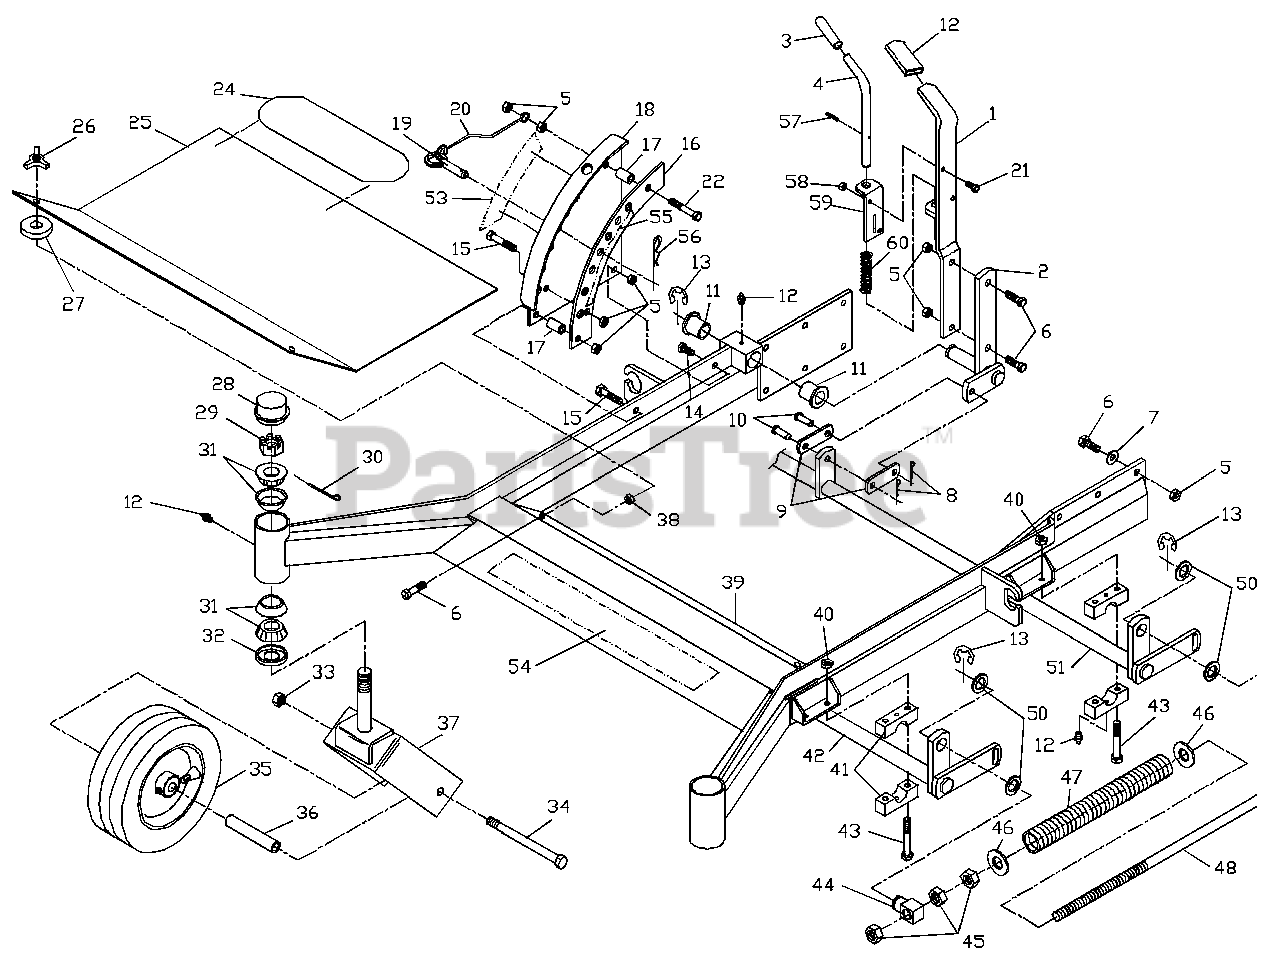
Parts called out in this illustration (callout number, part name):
1	LIFT LEVER
2	DECK LIFT ARM
5	3/8C CENTERLOCK NUT
6	3/8C X 1 1/4 HEX CAP SCREW
7	3/8 DISC SPRING WASHER
8	1/8 X 3/4 COTTER PIN
10	3/8 X 1 1/8 CLEVIS PIN
11	FLANGED BEARING
13	7/8 "E" RING
14	3/8C X 3/4 HEX CAP SCREW
15	3/8C X 2 HEX CAP SCREW
18	PLATE WELDMENT
21	HCS 1/4C X 3/4
22	3/8C X 2 1/4 HEX CAP SCREW
24	ANTI-SKID PAD
25	FOOT PLATE
27	RUBBER WASHER
28	GREASE CAP
29	1" C HEX SLOTTED NUT
30	1/8 X 2 COTTER PIN
31	BEARING W/CUP
33	1/2C NYLOC NUT
34	1/2C X 7 1/2 HEX CAP SCREW
35	TIRE ASSEMBLY COMPLETE
35	RIM
35	TIRE
35	ROLLER BEARING
35	FLANGED BEARING
36	CASTER SPACER
37	CASTER YOKE
38	3/8C WHIZ NUT
39	FRONT FRAME WELDMENT
40	5/16C CENTERLOCK NUT
41	LIFT BLOCK
42	FRONT LIFT ROD
43	5/16C X 2 1/2 HEX CAP SCREW
44	DECK MOUNT SWIVEL
45	5/8C HEX NUT
46	5/8 FLAT WASHER
47	DECK SUPPORT SPRING
48	DECK LIFT ROD
49	DECK MOUNT SWIVEL, THREADED
50	MACHINERY BUSHING
52	LIFT LEVER GRIP
53	DECAL, DECK HEIGHT
54	DECAL. HUSQVARNA
55	DECAL, HEIGHT
56	#4 HAIR PIN
57	3/16 X 1 ROLL PIN
58	1/4C HEX CENTERLOCK NUT
59	PIN MOUNT, UPPER
